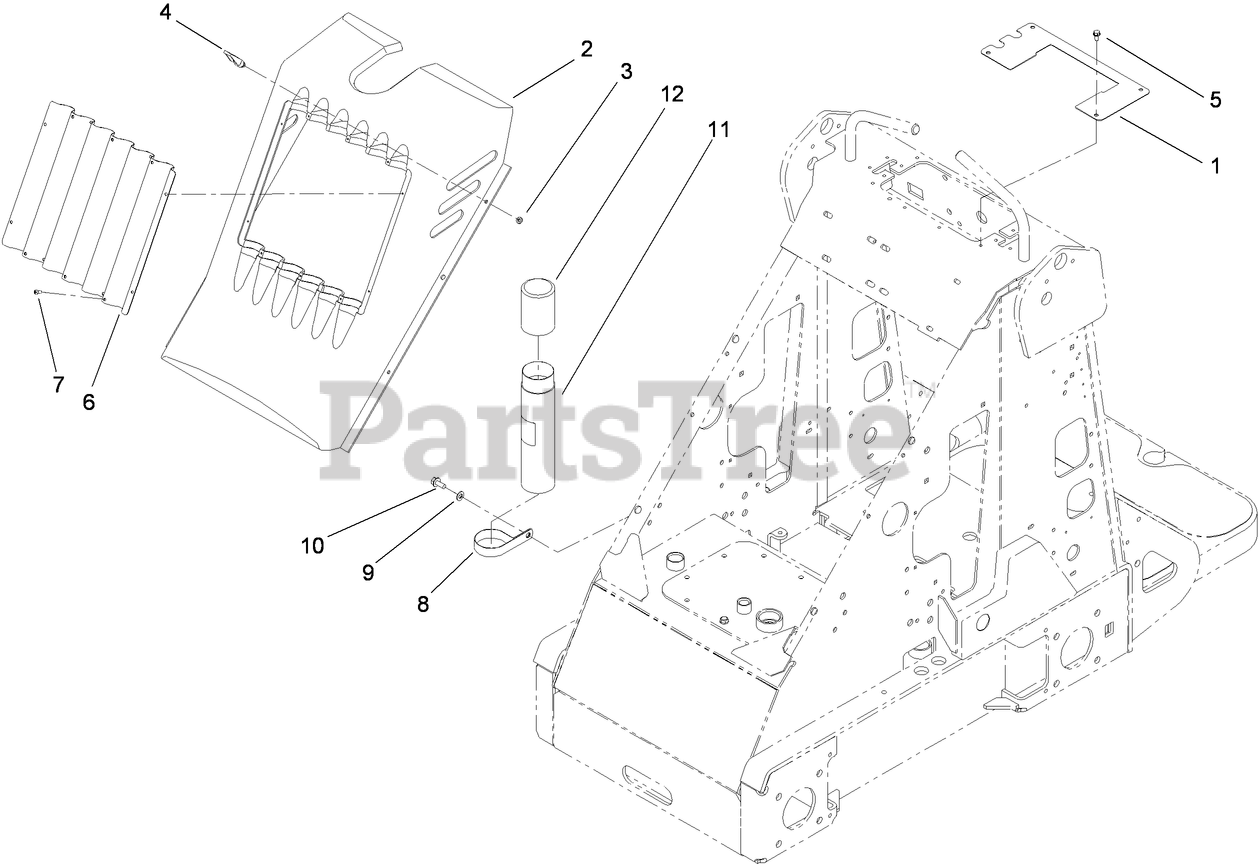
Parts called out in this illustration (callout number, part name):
1	PLATE-COVER
2	COVER-HOOD
3	WASHER
4	LATCH-SWELL
5	SCREW-HWH
6	GRILLE-SCREEN
7	SCREW-PPH
8	CLAMP-R
9	WASHER-PLAIN
10	SCREW-HWHTF
11	TUBE-MANUAL
12	CAP-HOUSING
